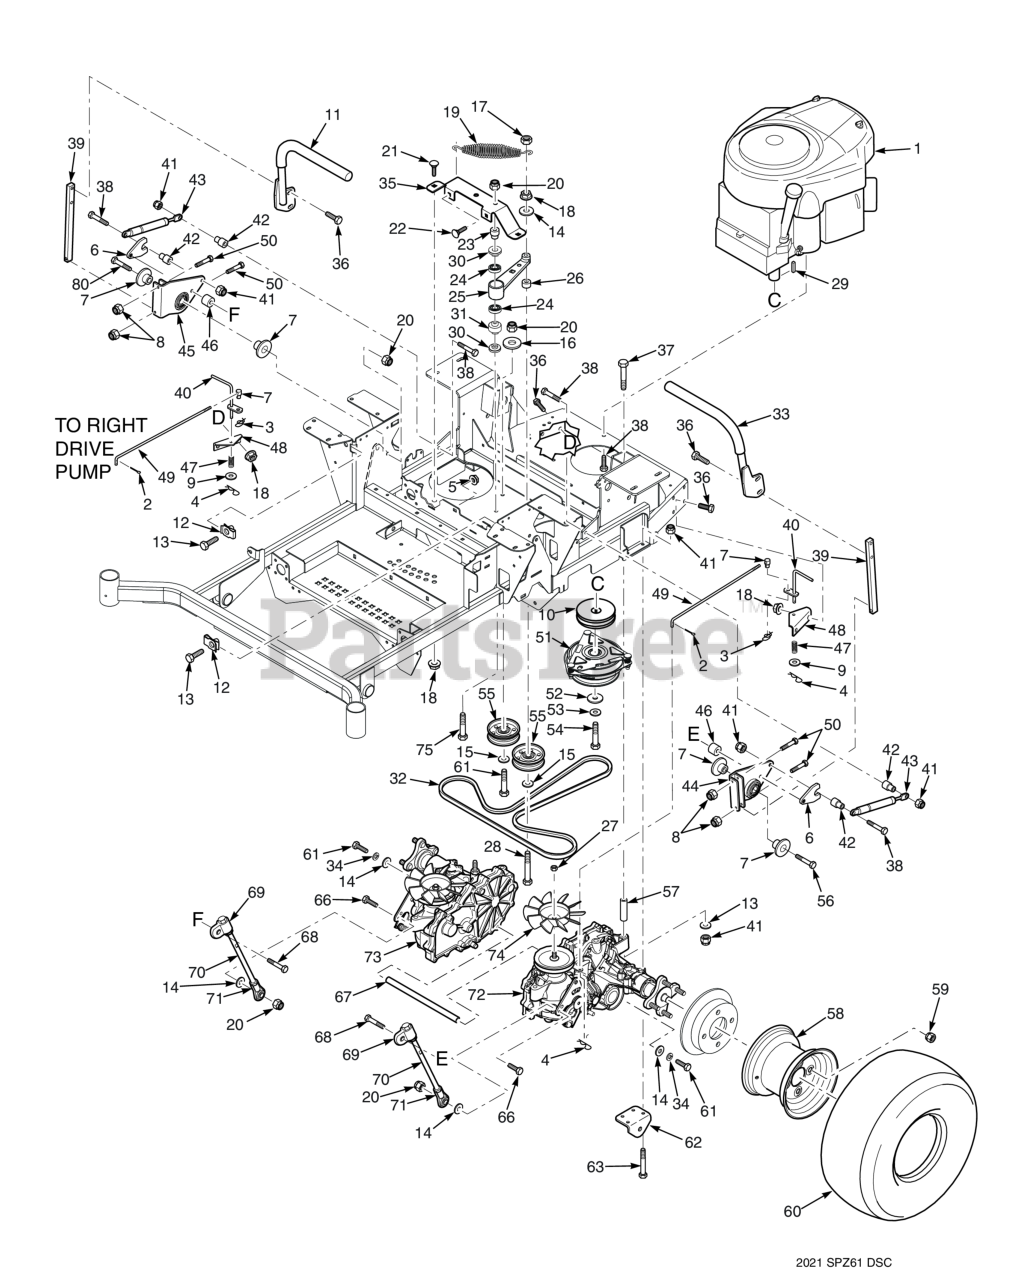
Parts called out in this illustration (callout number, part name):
1	Engine, Kohler - 23CV
2	COTTER PIN, 3/32 X 1"
3	Pin, Rue Cotter 3/8" Diameter
4	HAIR PIN, .08 DIAMETER X 1-3/16"
5	Nut, Serrated Flange 5/16-18 (Right Front Engine Mounting, Briggs and Kohler Only)
6	Nut, Control Linkage
7	Spacer, Linkage
8	HEX, NUT, ELASTIC STOP LOCK, 1/4-20
9	Flatwasher, 1/4" (.312 x .750 x .065")
10	Pulley, 4-1/2" OD - 1.125 Bore (SFZ61)
11	Handle Bar Assembly RH, w/Grip
12	U-Nut, 3/8-16 (short)
13	Bolt, Hex Head 3/8-16 x 1-1/4" Special Lock
14	Flatwasher, 3/8" Special (.391 x .938 x .105)
15	Flatwasher, 3/8 (.391 x .938 x .105 HD) Grade 8
16	Flatwasher, 3/8-.406 x 1-1-1/2 x 7 Gauge
17	Bolt, Hex Head 3/8-16 x 1" Ser. Flg.
18	NUT, 3/8-16 SERRATED FLANGE HEX HEAD
19	Spring, Transmission Idler
20	HEX NUT, ELASTIC STOP LOCK, 3/8-16
21	Bolt, Carriage 3/8-16 x 3/4"
22	Bolt, 5/16-18 x .75 RHSN Carriage
23	Shaft Pivot, Idler Arm
24	BEARINGS, BALL, NEUTRAL RETURN
25	Trans. Idler Arm Assy. (Includes 24, 79)
26	Spacer, Idler Pulley - SFZ52
27	Fan Nut (order through Hydro-Gear)
28	Reservoir Assembly
29	Key, 1/4" x 1/4" x 2-3/4" Pulley Mtg.
30	Spacer, Controls
31	Spacer, Bearing
32	Belt, Transmission Drive - SFZ52
33	Handle Bar Assembly LH, w/Grip
34	Lockwasher, 3/8" Spring, Kawasaki FX / FS
35	Support, Idler Arm
36	Capscrew, 3/8-16 x 1.0" Serrated Flange Hex Hd
37	HEX HEAD BOLT, 5/16-18 X 5"
38	Bolt, Hex Head 5/16-18 x 1-1/2" (Right Front Engine Mounting, Briggs and Kohler Only)
39	Bar, Control Lever
40	Dump Valve Lever
41	HEX NUT, ELASTIC STOP LOCK, 5/16-18
42	Spacer, Pump Dampener
43	Gas Damper
44	Control Link, LH
45	Control Link, RH
46	Spacer, Idler Pulley - SFZ52
47	Spring, Dump Valve Link
48	Bracket, Dump Mounting
49	Rod, Brake Adjustment
50	Bolt, Hex Head, 1/4-20 x 1-1/2"
51	Electric Clutch Assembly - SFZ52 & SFZ61
52	Flatwasher, 7/16-.469 x 1.75 x .25 (48, 52)
53	Flatwasher, 7/16-.469 x 1.75 x .25 (48, 52)
55	Pulley, 3-1/2" Dia.
56	Capscrew, Hex Head 3/8-16 x 2.0"
57	Spacer, Axle - SFZ52
58	Rim w/Valve Stem (52)
59	Wheel Nut, 1/2-20 x 13/16
60	Wheel Assembly, 22 x 10.5-12 (SPZ52)
61	Capscrew, Hex Head 3/8-16 x 2-1/2"
62	Bracket, Push Arm Link
63	Bolt, Hex Head 5/16-18 x 3.00"
64	Clip, Brake Lever (order through Hydro-Gear)
65	Lever, Brake (order through Hydro-Gear)
66	Bolt, Hex Head, 3/8-16 x 1-1/2"
67	Spacer, Axles
68	Capscrew, Hex Head 3/8-16 x 2.0"
69	Rod End, Adjustable 3/8-24
70	Linkage, Pump - SFZ52
71	Stake, Rod End Assembly
72	Transaxle Assy., LH (ZL-GCEC-SLKF-1NTX)
73	Transaxle Assy., RH (ZL-KCEC-SLKG-1NTX)
74	Capscrew, Hex Head 3/8-16 x 3.25"
